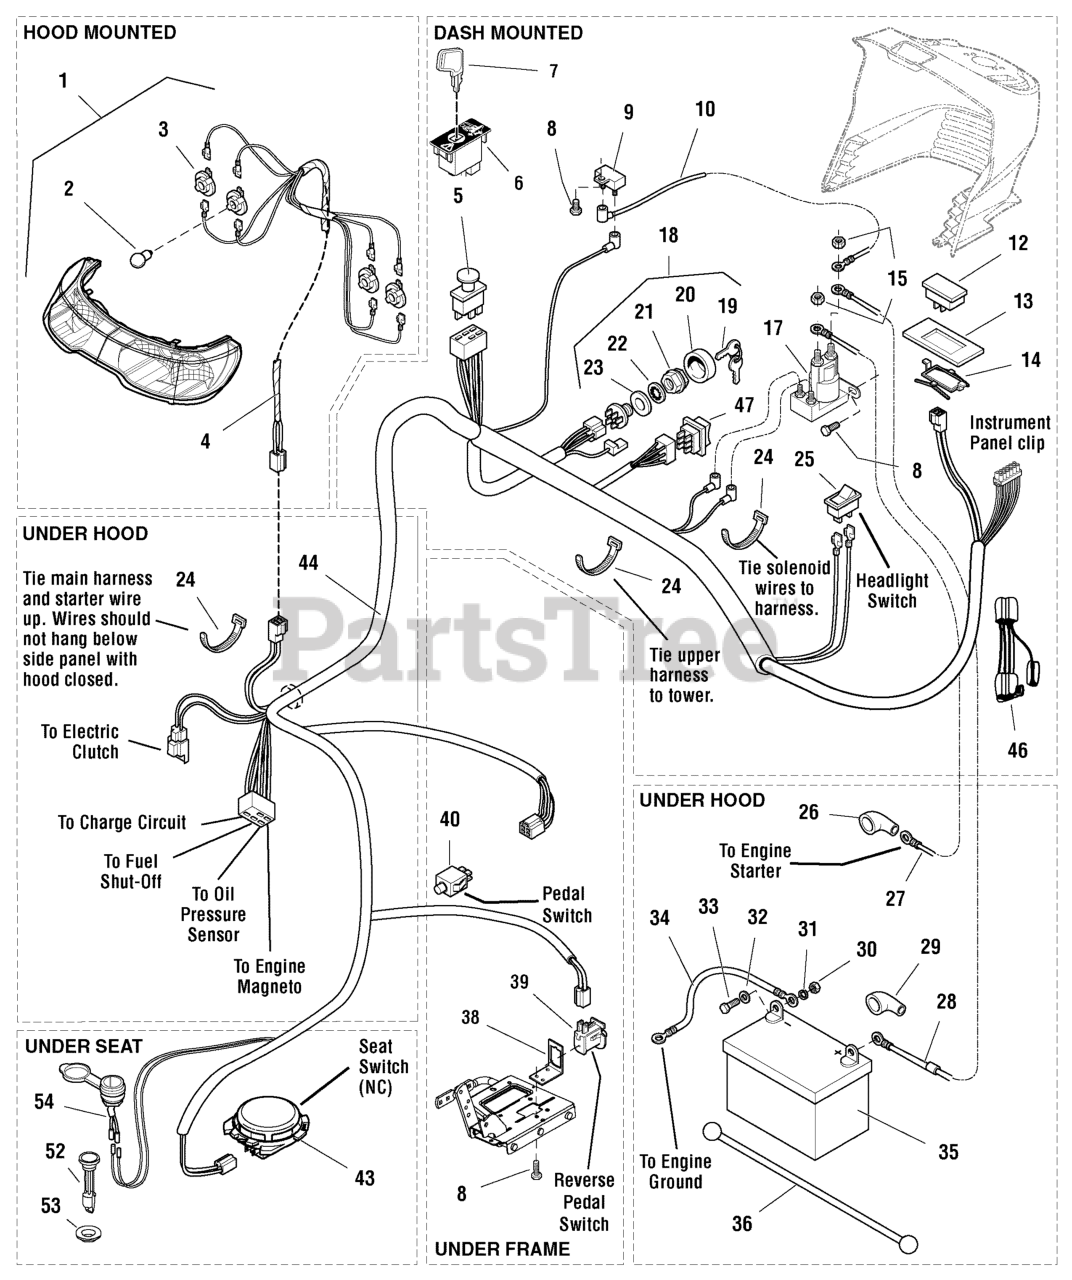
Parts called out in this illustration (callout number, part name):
1	HEADLIGHT ASSEMBLY, 4 Bulb
2	BULB, Headlight, 12.8V
3	SOCKET ASSEMBLY, Headlight, Sealed
4	HARNESS, Headlight
5	SWITCH, PTO
6	SWITCH, RMO Module Only
7	KEY, RMO Module, Plastic
8	CAPSCREW, Hex Washer Head Taptite, 1/4-20 x 1/2, Black
9	BREAKER, Circuit, 12 Volt 20 Amps
10	WIRE, 12GA 5-15/16 Long, Red
12	METER, Hour Digital, with Oil & Lube Alarms
13	PLUG, Dash, Hour Meter
14	CLIP, Hour Meter
15	NUT, KEPS Lock 5/16-24
17	SOLENOID
18	SWITCH ASSEMBLY, Ignition, 6 Pin INDAK
19	KEYS, Set of 2
20	COVER, For Ignition Switch, Plastic
21	NUT, Hex Flange, 5/8-32, Ignition Switch
22	LOCKWASHER, Internal Tooth, 5/8, Thin
23	WASHER, Shim
24	TIE, Strap, 7-5/16 Long
25	SWITCH, Headlights, 2 Terminal
26	BOOT, Insulator Cable Terminal, 1-15/16 Long, Red
27	CABLE, #6 x 25" Long, Ring Terminals
28	CABLE, #6 x 8" Long, Ring Terminals
29	BOOT, Insulator Battery Terminal
30	NUT, Hex, 1/4-20
31	LOCKWASHER, 1/4
32	WASHER, 1/4
33	CAPSCREW, Hex Head, 1/4-20 x 3/4
34	CABLE, #6 x 26 Long, Ring Terminal
35	BATTERY, 12 Volt
36	STRAP, Battery, 14 Long, Rubber
38	BRACKET, Switch Mount
39	SWITCH, Reverse Pedal
40	SWITCH, Push Button, Foot Pedal
43	SWITCH, Seat, Grey, NC
44	HARNESS, Wiring
46	HARNESS, Jumper
47	SWITCH, Mower Height Adjust
52	FUEL GAUGE
54	OUTLET, 12 Volt
